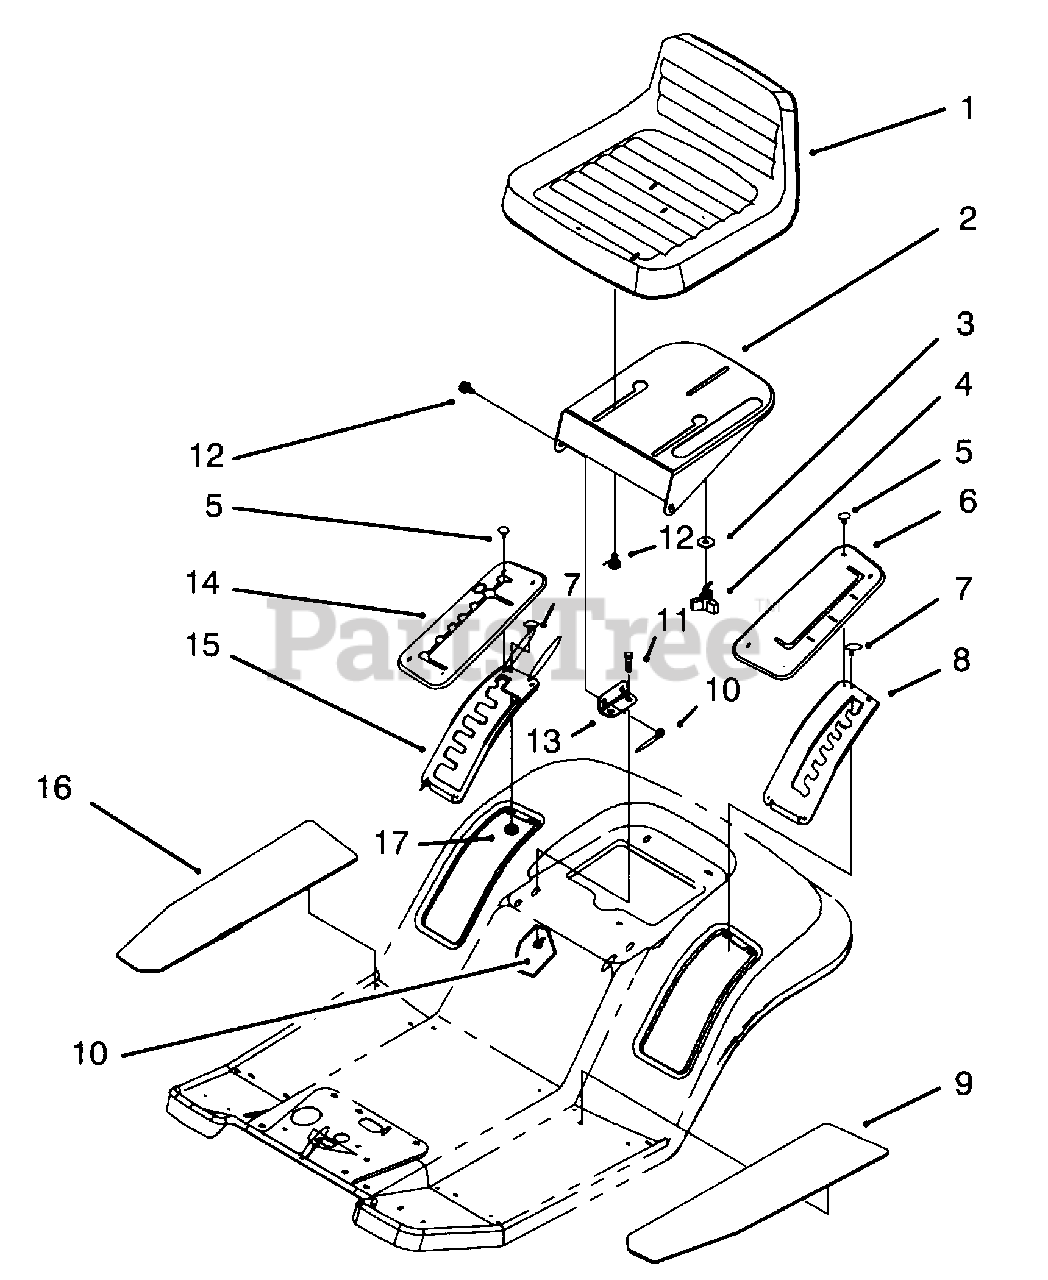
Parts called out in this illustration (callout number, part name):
1	Seat (Model No. 81140 Only)
2	Support-Seat
3	Washer-Fender
4	Knob-Studded
6	Cover-H.O.C.
7	Rivet-Pop
8	Gate-H.O.C.
9	Tread-L.H. Foot
10	Nut-Lock
11	Screw-Hex Hd. Cap
12	Bolt-Shoulder
13	Bracket-Seat Hinge
14	Cover-Shift Gate
15	Gate-Shift
16	Tread-R.H. Foot
17	Washer-Backup
